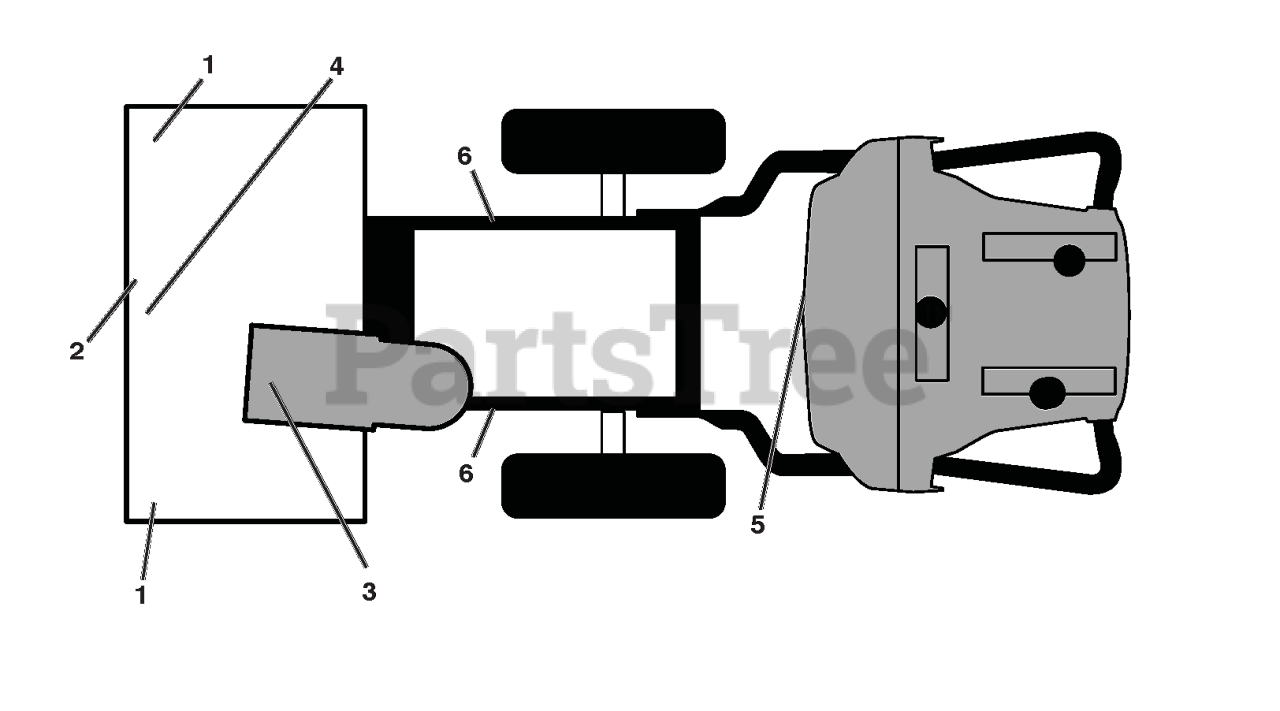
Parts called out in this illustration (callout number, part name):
1	DECAL.AUGER.SAFETY.
2	DECAL.AUGER HSG.HUSQ.ST 224
3	DECAL.CHUTE.SAFETY.EU/SC.17
4	DECAL.AUGER."
5	DECAL.BADGE.55MM.CROWNH.HUSQ
6	DECAL.BELT.GUARD.
